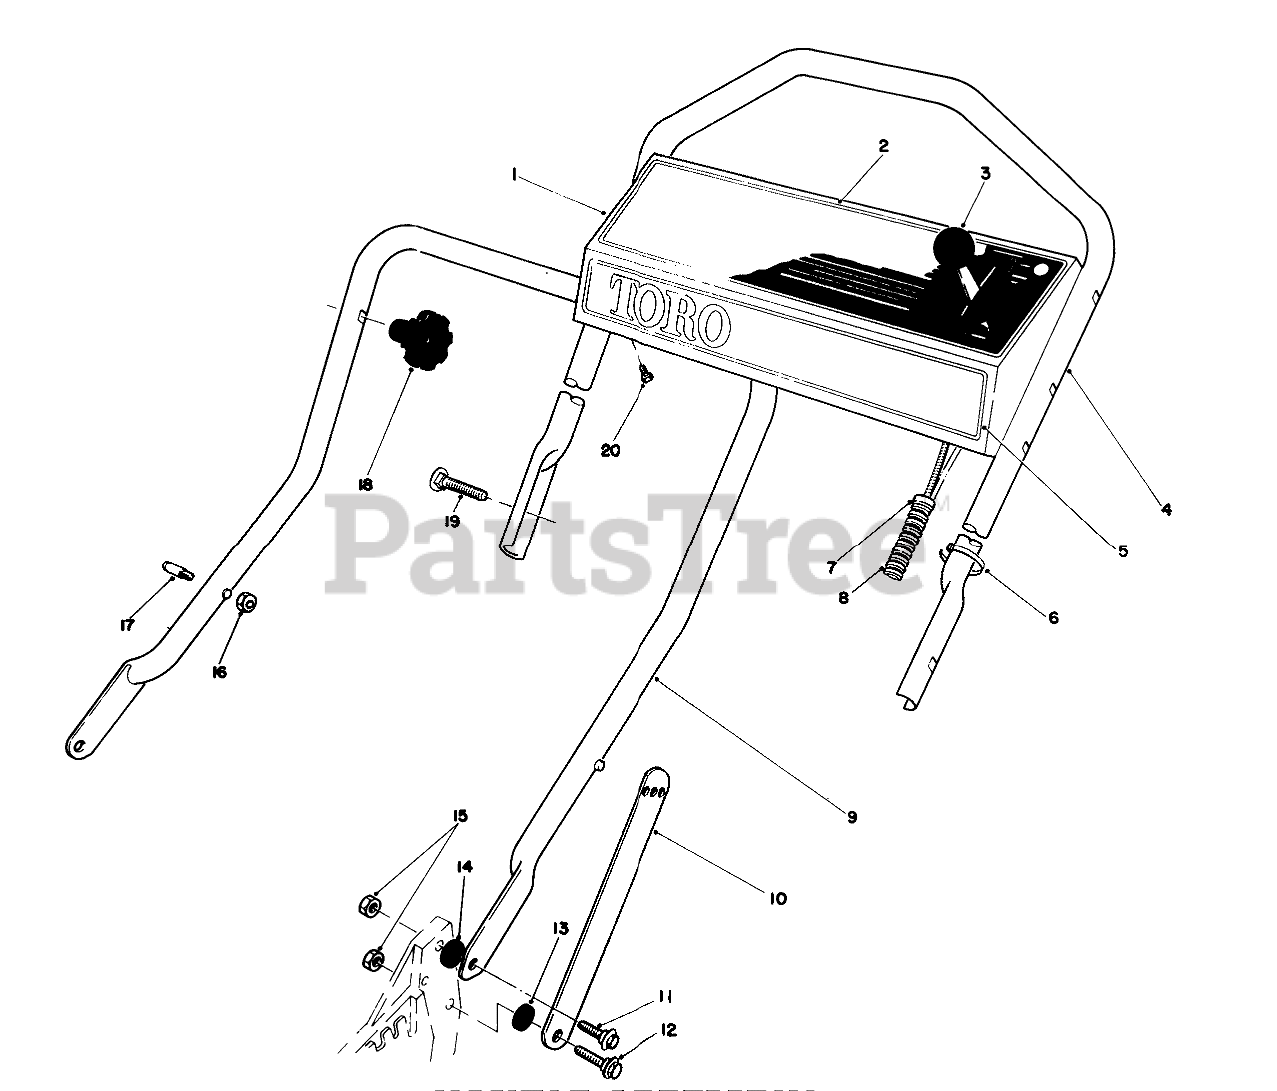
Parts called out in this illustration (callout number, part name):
1	Panel-Control (Incl. Ref. #2)
2	OBS INSTRUCTION DECAL
3	SERVICE THROTTLE CONTRO
4	Handle-Upper
5	Decal-Toro
6	RIVET
7	FITTING-RING
8	CONTROL CABLE COVER
9	LOWER HANDLE ASM
10	Handle Latch
11	SCREW-SHOULDER
12	SCREW-SHOULDER
13	SPACER
14	SPACER
15	NUT-LOCK, NI
16	NUT-LOCK, NI
17	HANDLE PIN
19	5/16-18 X 2 HNDLE SCREW
20	SCREW-HWHTF
